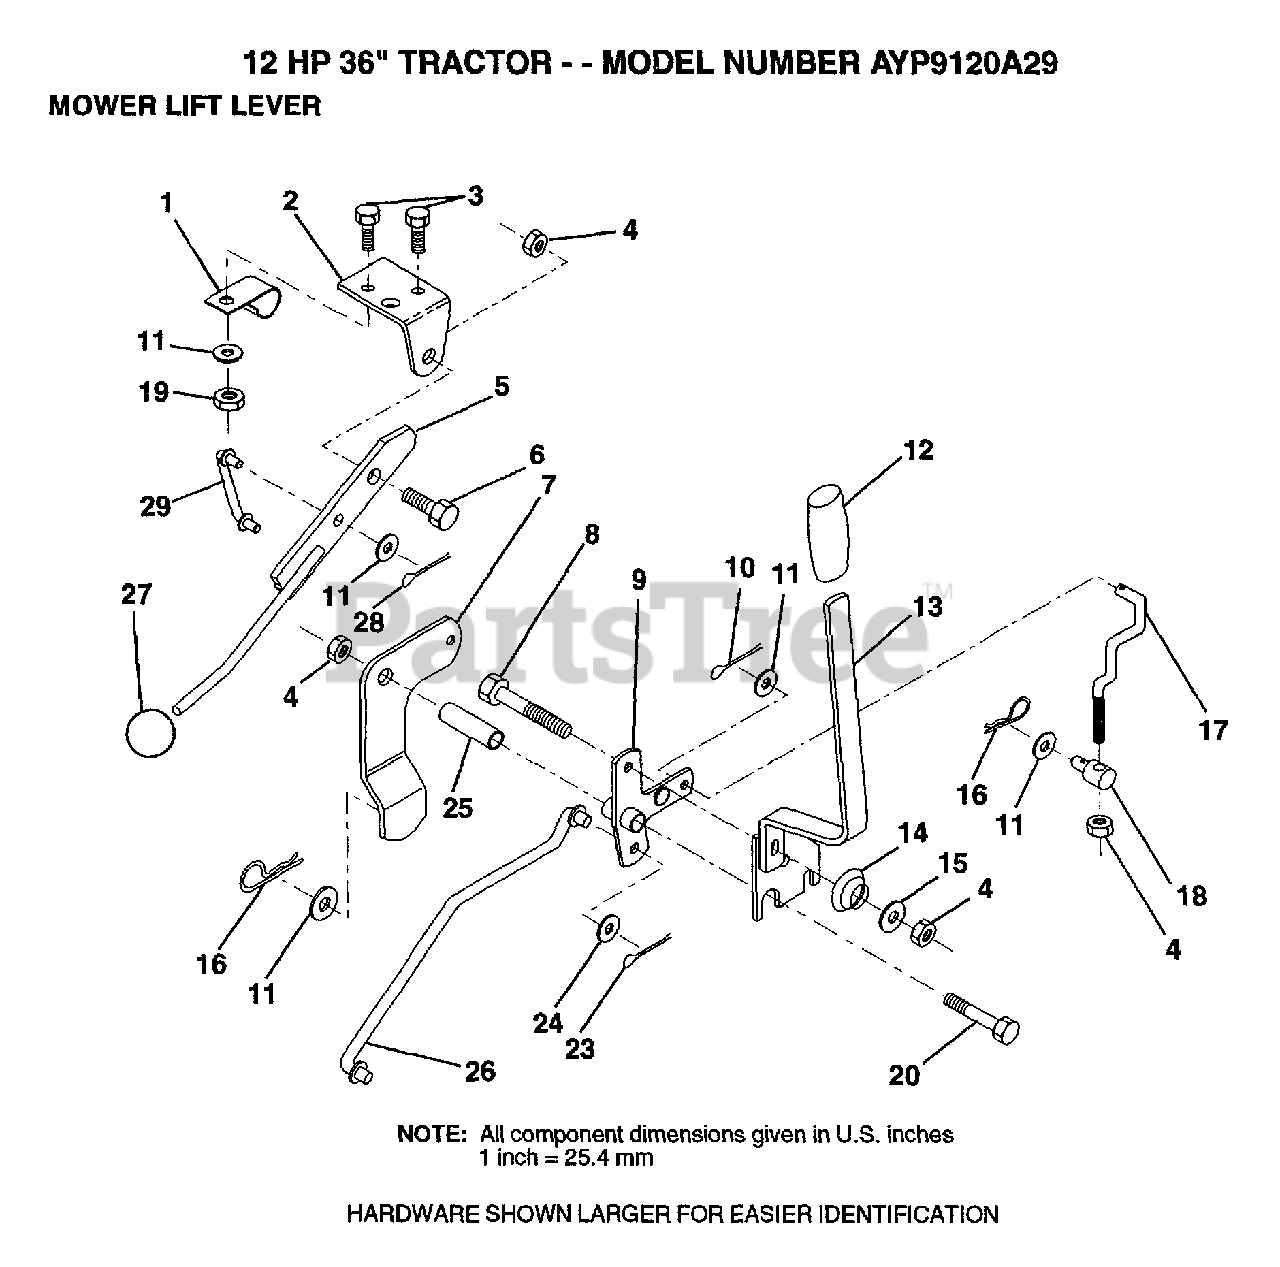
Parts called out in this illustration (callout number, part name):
1	"CLIP,INSULATOR"
2	BRKT CLUTCH
3	BOLT
5	CLUTCH LEVER AS
6	"BOLT, SHOULDER LT"
7	MWR CLUTCH ARM AS
8	BOLT
9	"BELLCRANK,LIFT"
10	COTTER PIN
11	WASHER
13	"HDLE,LIFT T"
14	SPRING COMPRESSIO
15	WASHER T
16	SPRING.RETAINER
17	"LINK,LIFT FRT"
18	TRUNION
20	BOLT
23	PIN COTTER 1/8
25	TUBE SPACER
26	"ROD,MOWER LIFT "
27	KNOB T(3/8 HOLE)
29	CLUTCH LINK
